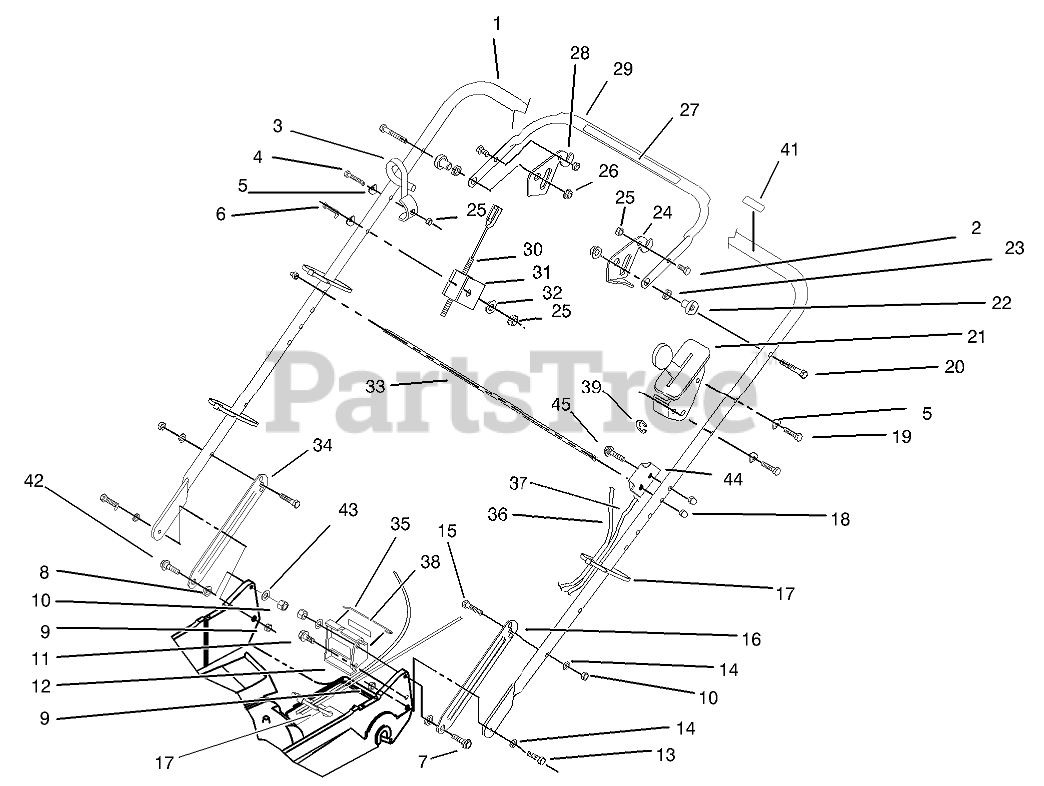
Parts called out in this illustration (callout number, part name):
2	SCREW-HH
3	GUIDE-ROPE
4	SCREW-HH
5	WASHER
6	SCREW-HH
7	SCREW-SHOULDER
8	SPACER
9	NUT-LOCK, NI
10	NUT-LOCK, NI
11	SCREW-HWHTF
12	BRACKET-ADJUSTMENT, TRACTION
13	SCREW-HH
14	WASHER-BELLEVILLE
15	SCREW-HH
16	LATCH-HANDLE, LH
17	TIE-CABLE
18	NUT-CAP
19	SCREW-HH
20	SCREW-HH
21	Control-Throttle
22	SPACER-SUPPORT
23	SPACER-NYLON
24	LEVER-CONTROL
25	NUT-LOCK, NI
26	NUT-LOCK, NI
27	Decal-Traction
28	LEVER-CONTROL
29	BAR-CONTROL
30	CABLE-BRAKE
31	SUPPORT-CABLE
32	WASHER-FLAT
33	ROD-SUPPORT, BAG
34	LATCH-HANDLE, RH
35	RETAINER-CABLE
36	CABLE-TRACTION
37	CABLE-THROTTLE
38	DECAL-POSITION, GEAR
39	E-RING
41	DECAL-PROTECTION, EAR
42	SCREW-SHOULDER
43	WASHER-PLAIN
44	PLATE-ALIGNING, BAG
45	SCREW-CARR
